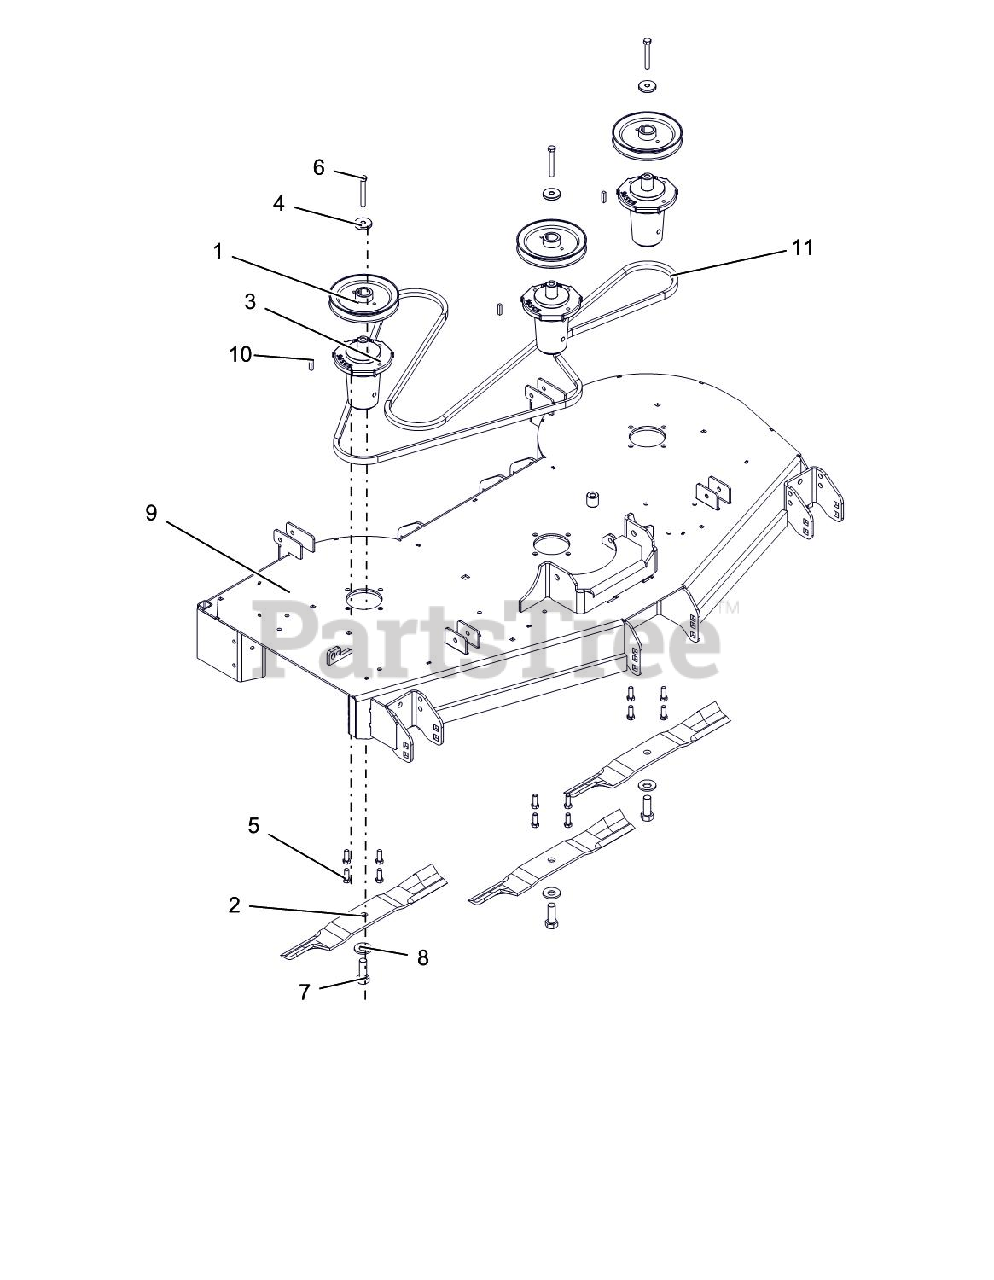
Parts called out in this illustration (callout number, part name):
1	PULLEY, 1.00 ID X 6.00 OD
2	BLADE, 18.00" MOWER (HI-LIFT)
3	ASM, MAINT FREE SPINDLE
4	RETAINER, SHEAVE
5	BLT-HEX .38-16X1.0 GR8 YZ EP30
6	BLT-HEX .38-16X2.75 GR8 YWZC
7	BLT-HEX .62-18X1.75 GR8 YWZC
8	WSHR-BLVL .669X1.535X.138
9	KIT, 52" MOWER DECK W DECALS
10	KEY, SQ .25X.25X1.00 RC 40-50
11	BELT, B-SECTION EPDM RAW EDGE
